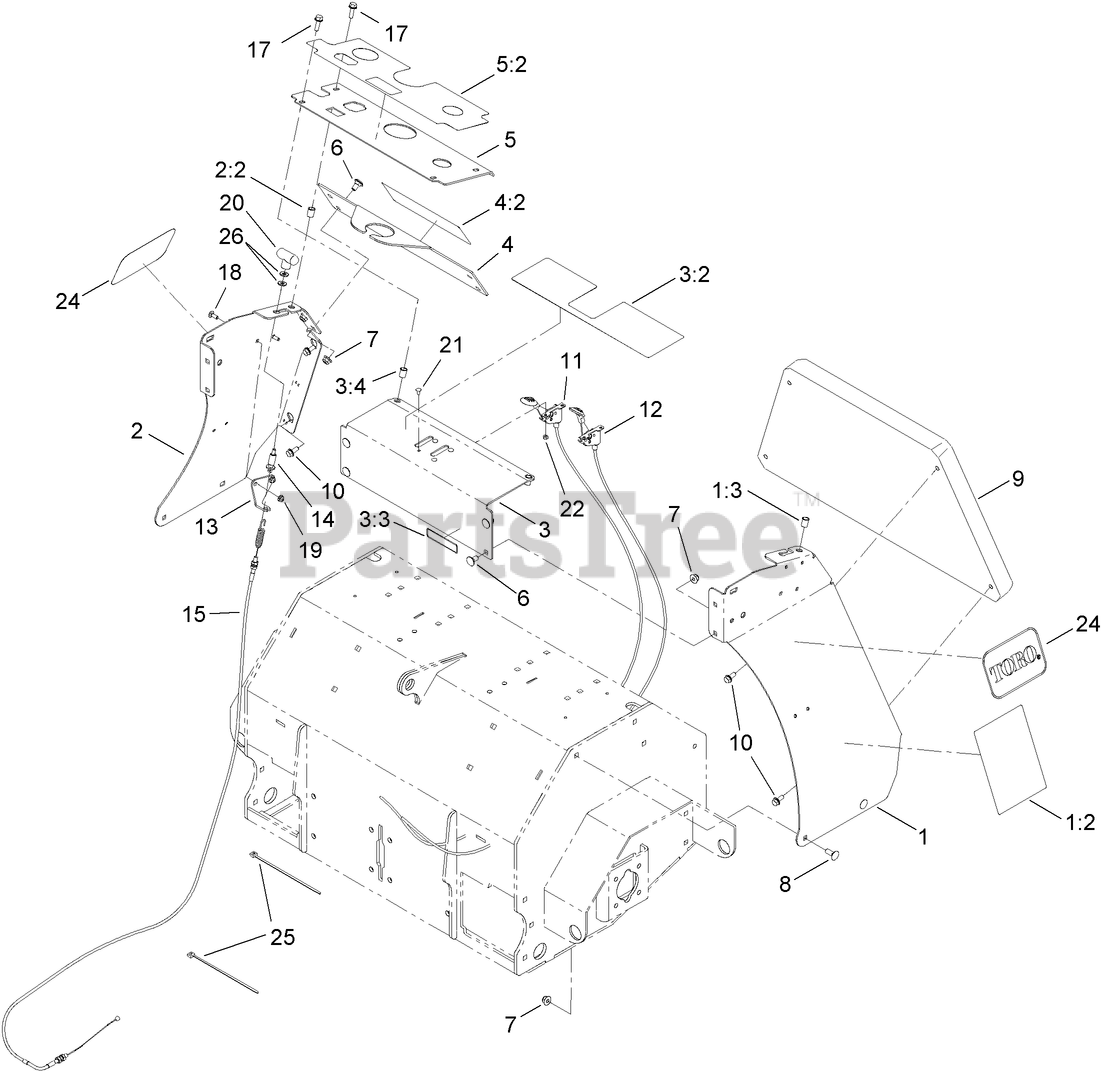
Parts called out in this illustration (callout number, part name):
1	LH SIDE PANEL ASM
1:2	DECAL-SERVICE AID, CE
1:3	NUT-INSERT
2	RH SIDE PANEL ASM
2:2	NUT-INSERT
3	PLATE ASM
3:2	DECAL-WARNING, CONTROL PANEL
3:3	DECAL-WARNING, TINES
3:4	NUT-INSERT
4	KNEE PAD BRACKET ASM
4:2	DECAL-DANGER
5	CONSOLE ASM
5:2	DECAL-CONTROL PANEL DANGER
6	SCREW-CARR
7	NUT-HF, NI
8	BOLT-CARR
9	CUSHION-BLACK
10	SCREW-HHF
11	CONTROL-CHOKE
12	CONTROL-THROTTLE
13	BRACKET-CABLE, BRAKE
14	LINK-CABLE, BRAKE
15	CABLE-BRAKE
17	SCREW-HHF
18	BOLT-CARR
19	NUT-HF
20	KNOB-TEE
21	BOLT-CARR
22	NUT-LOCK, NI
24	DECAL
25	TIE-PLASTIC
26	WASHER-FLAT
